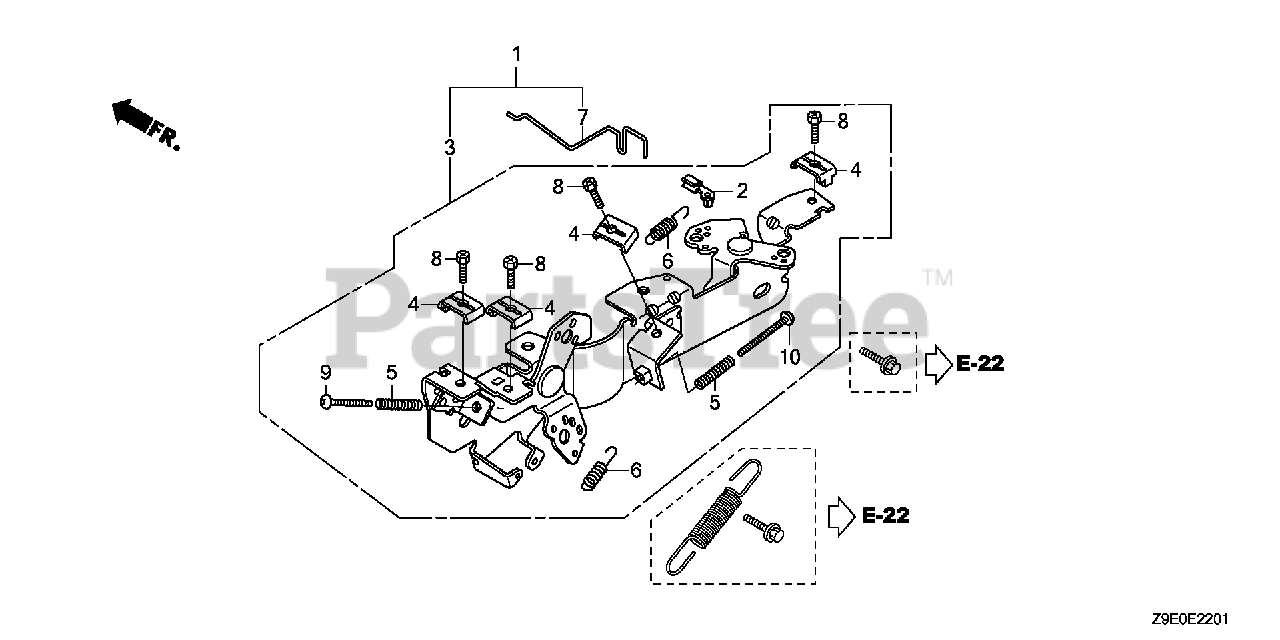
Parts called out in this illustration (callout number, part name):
1	CONTROL KIT
2	JOINT, ROD
3	CONTROL ASSY.
4	HOLDER, CABLE
5	SPRING, CONTROL ADJUSTING
6	SPRING, CABLE RETURN
7	ROD, CHOKE CONTROL
8	BOLT, RECESSED (5X16)
9	SCREW, PAN (5X30)
10	SCREW, PAN (5X45)
